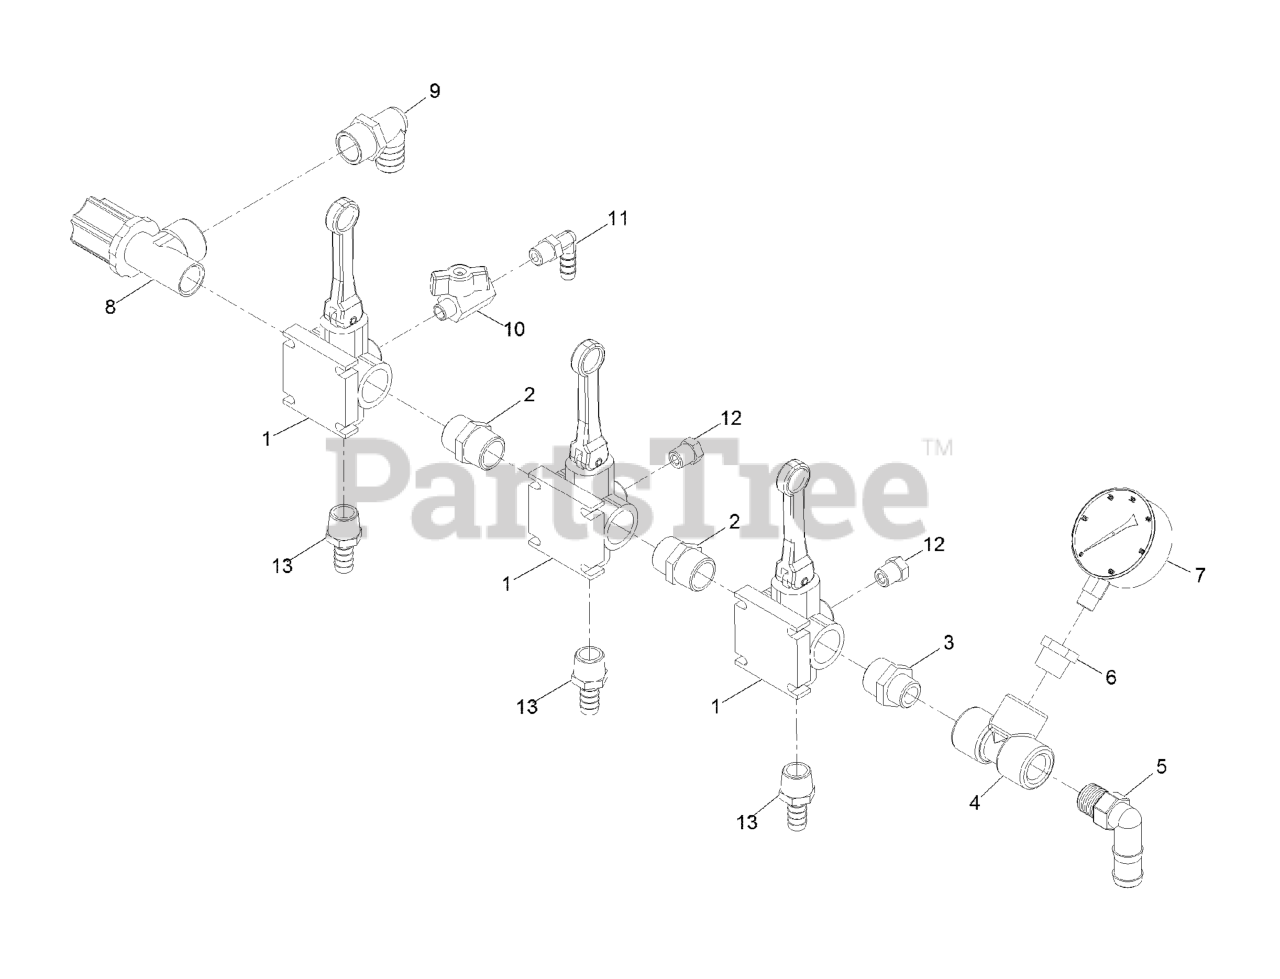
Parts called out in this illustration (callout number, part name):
1	VALVE-DIRECTO
2	FITTING-NIPPLE
3	FITTING-NIPPLE
5	ELBOW-90
6	FITTING-REDUCER
7	GAUGE
8	VALVE-THROTTLE
9	FITTING-ELBOW, 90
10	VALVE-CHROME, 1/4
11	FITTING-ELBOW, 90
12	PLUG-VALVE
13	FITTING-HOSEBARB
